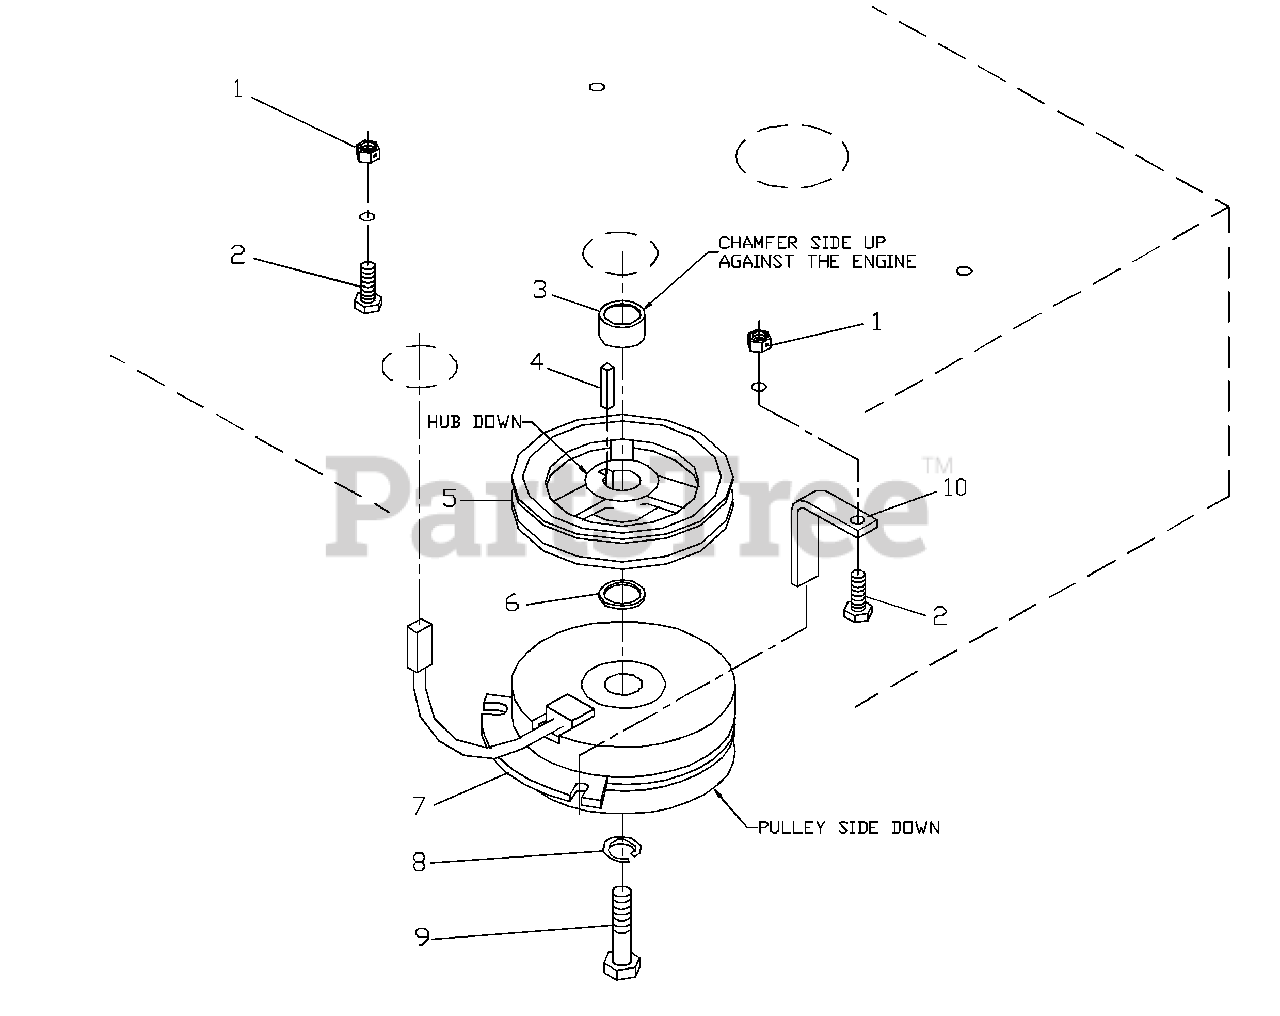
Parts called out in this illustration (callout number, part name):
1	NUT 5/16C CENTERLOCK
2	HCS 5/16C X 1 1/4
4	KEY 1/4 SQ. X 1 1/8
6	10GA. MACHINERY BUSHING
7	ELECTRIC CLUTCH
8	7/16 LOCKWASHER
9	HCS 7/16F X 2 1/2
10	HCS 5/16C X 1 3/4
11	CLUTCH TIE DOWN
